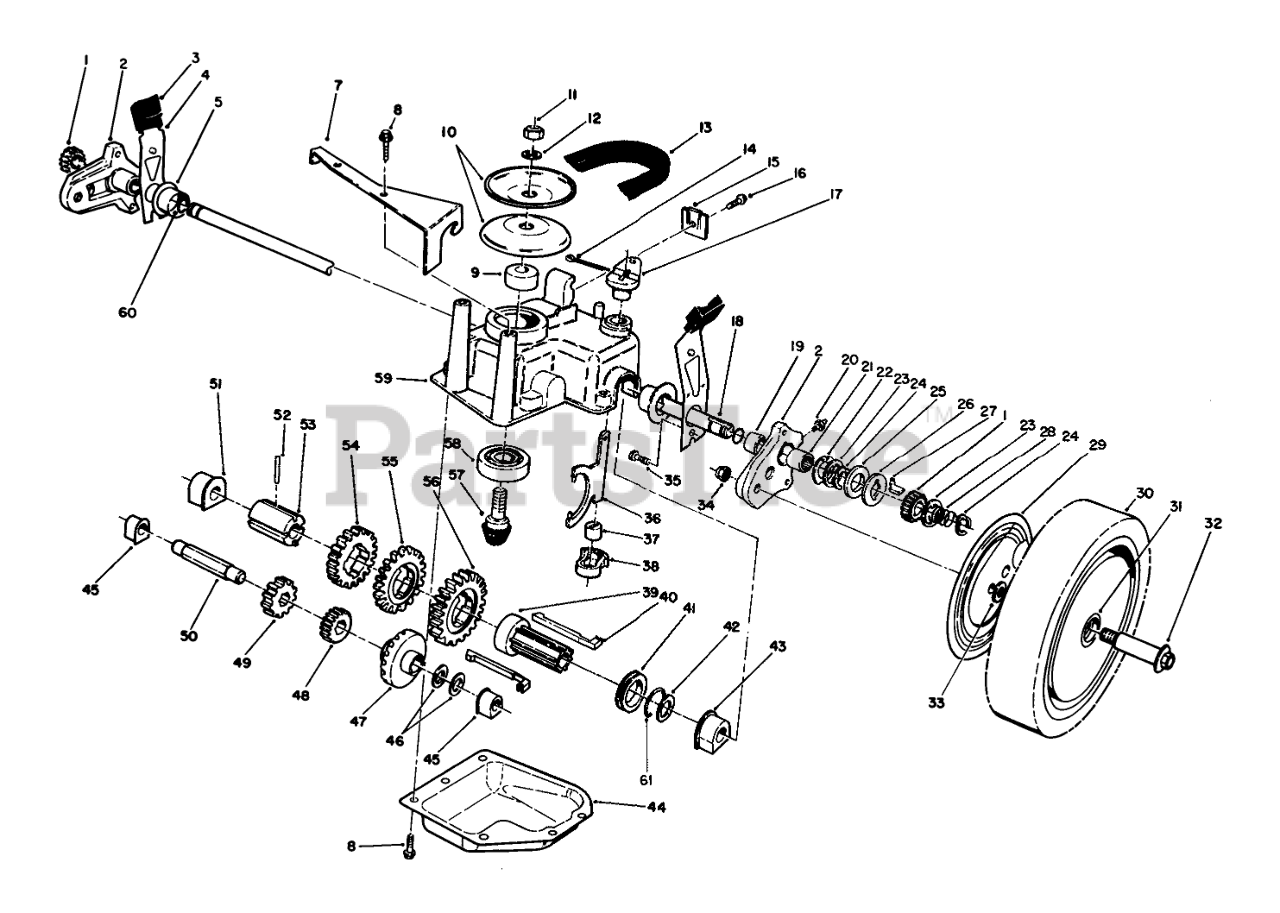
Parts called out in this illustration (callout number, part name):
1	Pinion
2	Pivot Arm Assembly (Incl. Ref. #19, 20, 21)
3	KNOB-ARM
4	SPRING ARM ASM SP
5	CAP-END
7	Bracket-Belt Guide
8	SCREW-HWHTF
9	SPACER
10	Pulley Half
11	NUT-HEX
12	WASHER-FLAT
13	V-BELT E
14	PIN-COTTER
15	Cable Clamp
16	SCREW-HWHTF
17	SHIFT LEVER
18	SHAFT-OUTPUT
19	BUSHING
20	FITTING-GREASE
21	BEARING-ROLLER
22	Thrust Washer
23	WASHER-THRUST, KEYED
24	RING-CLIP, LOCKING
25	RING-FRICTION
26	WASHER-CLUTCH
27	KEY-ROCKING, LH
28	SPRING-COMPRESSION
29	WHEEL COVER
30	Wheel-Tire & Gear Assy. (Incl. Ref. #31)
31	HOC ADJUSTMENT ASM
32	WHEEL BOLT
33	WASHER
34	Nut
35	SCREW-HWH
36	YOKE-SHIFT
37	BUSHING-YOKE
38	RETAINER-FORK, SHIFT
39	Sleeve-Shift Key
40	SHIFT KEY
41	SHIFT KEY SLEEVE
42	WASHER-PLAIN
43	BUSHING-OUTPUT
44	Cover-Gearcase
45	BUSHING
46	WASHER-THRUST
47	Gear-Bevel
48	PINION-20T
49	PINION-25T
50	SHAFT-INTERMEDIATE
51	BUSHING
52	PIN-SPRING
53	SLEEVE-GEAR
54	GEAR-39T
55	GEAR-44T
56	GEAR-49T
57	Gear-Pinion
58	BEARING-BALL
59	CASE-GEAR, UPPER
60	O-RING
61	CLIP-SPRING
